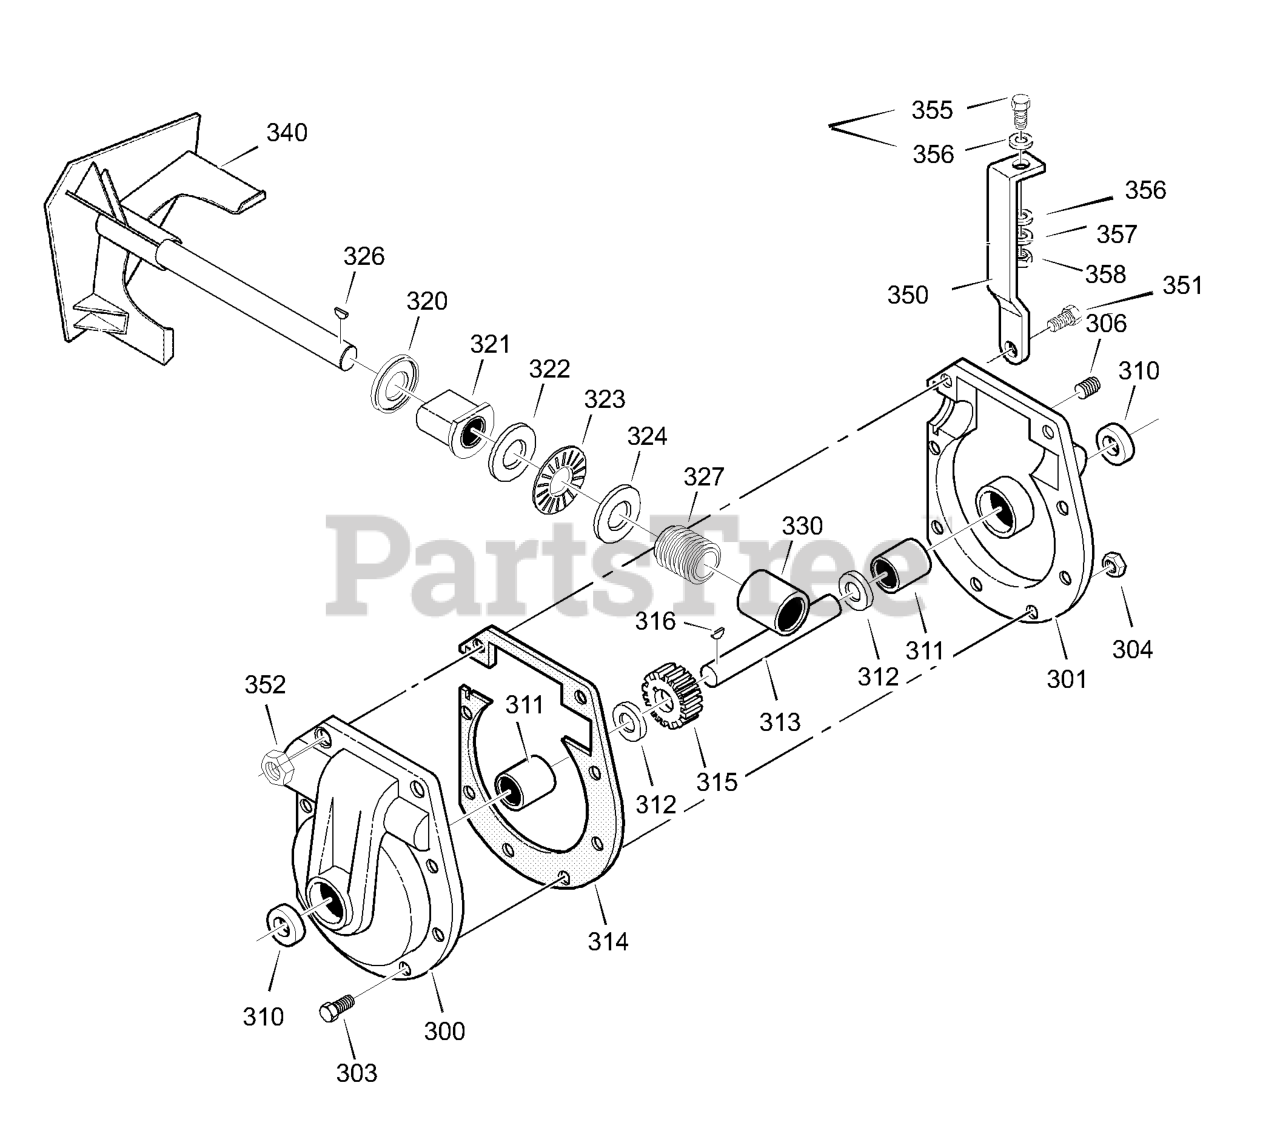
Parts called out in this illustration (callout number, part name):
300	CASE, GEAR, RH
301	CASE, GEAR, LH
303	SCREW, 5/16-24 x 1.00
304	NUT, 5/'16-24
306	PLUG, PIPE 0.25-18
310	SEAL, OIL
311	BEARING, SLEEVE
312	WASHER, FLAT
313	SHAFT, AUGER OUTPUT
314	GASKET, GEAR BOX
315	WORM GEAR
316	KEY, WOODRUFF #91
320	RING, QUAD 0.924 ID
321	BEARING, FLANGE
322	WASHER, FLAT
323	BEARING, ROLLER
324	WASHER, FLAT
330	BEARING, SLEEVE
350	BRACE, GEAR BOX
351	SCREW, 5/16-24 x 1.75
352	NUT, HEX 5/16-24
355	SCREW, 5/16-18 x 1.25
356	WASHER, FLAT
357	WASHER
358	NUT, REGHEX 5/16-18
